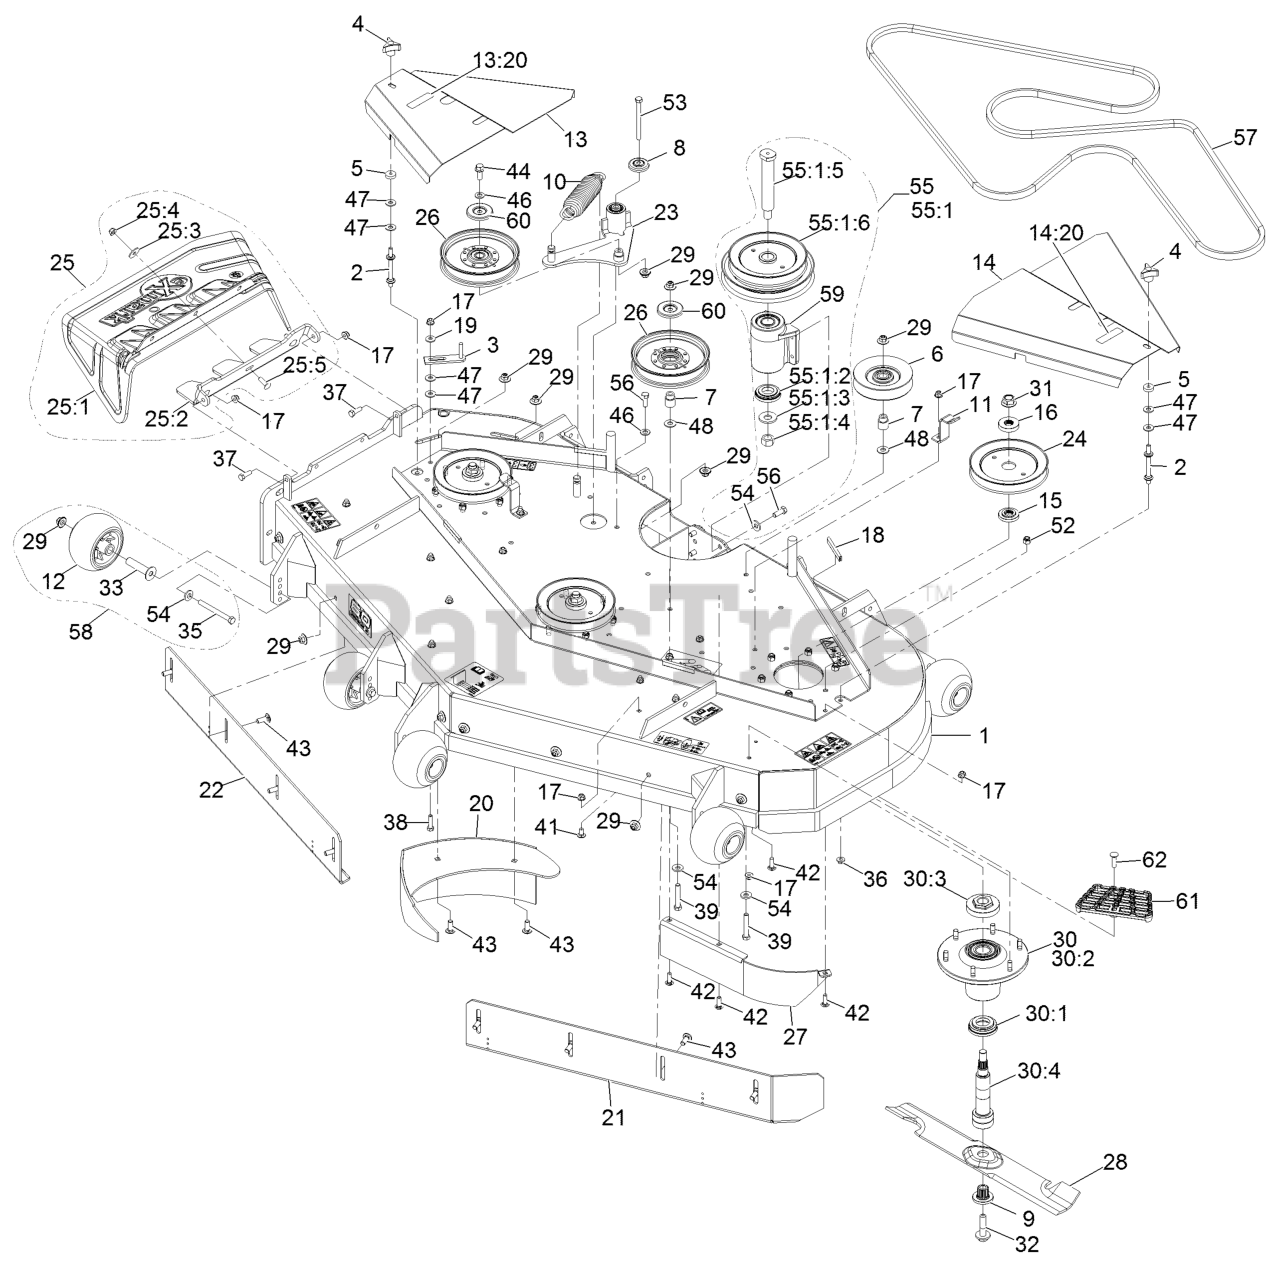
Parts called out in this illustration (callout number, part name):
1	ASM, DECK 605 W/DECALS
2	STUD-SHIELD, BELT (SHORT)
3	GUIDE-BELT
4	KNOB-3 PRONG
6	PULLEY-IDLER
7	BUSHING-IDLER
8	GUARD-TOP
9	BUSHING,SPLINED
10	SPRING-EXTENSION
11	LATCH,BELT SHIELD
12	ROLLER-SCALP, ANTI
13	SHIELD, BELT RH 605 W/DEC
13:20	DECAL-NO STEP
14	SHIELD, BELT LH 605 W/DEC
14:20	DECAL-NO STEP
15	SPACER,SPLINED STEPPED
16	SPACER,SPLINED
17	NUT-HF, NI
18	STRIP-SEAL
19	WASHER-SPRING
20	WLD,DOGLEG 605
21	WLD,BAFFLE FRT ADJ LH 605
22	WLD,BAFFLE FRT ADJ RH 605
23	KIT, IDLER ARM W/BEARINGS
24	SHEAVE, BLADE DRIVE 6.13
25	ASM, DISCHARGE CHUTE
25:1	CHUTE,DISCHARGE LZ
25:2	HINGE,DISCHARGE CHUTE
25:3	WASHER-FLAT
25:4	NUT-HF, NI
25:5	SCREW-CARR
26	IDLER-PULLEY, FLAT 6.00X1
27	BAFFLE,SCROLL 605
28	Blade-High Lift Solid, 20.75
28	Blade,High Lift Notched 20.75
28	Blade-Extreme 2, 20.75
29	Nut-Nyloc 3/8-16 Flg
30	ASM,SPINDLE HOUSING
30:1	GUARD,BOTTOM
30:2	ASM,CUTTER HOUSING
30:3	NUT, SPINDLE 7/8-14
30:4	SPINDLE,DOUBLE SPLINE
31	NUT-FLANGE, CENTERLOCK
32	SCREW,SEMS 1/2-20 X 2.19
33	AXLE, ROLLER
35	SCREW-HH 3/8-16 X 3 3/4 GR 8
37	SCREW-HH
38	SCREW-HH
39	SCREW-HH
41	SCREW-CARR
42	SCREW-CARR
43	SCREW-CARR
44	SCREW-HHF
46	WASHER-FLAT
47	WASHER-FLAT
48	WASHER-FLAT
52	NUT-LOCK, NI
53	SCREW-HH
54	WASHER-BELLEVILLE
55	KIT,JACKSHAFT 60/72-3750
55:1:2	SPACER-GUARD, BOTTOM
55:1:3	WASHER-SPRING
55:1:4	NUT-HEX
55:1:5	JACKSHAFT
55:1:6	SHEAVE, JACKSHAFT DOUBLE
56	SCREW-HH
57	BELT,BLADE DRIVE
58	KIT, ANTI-SCALP ROLLER
59	KIT, JACKSHAFT ASSY
60	SHIELD-DUST
61	STEP-DECK
62	Bolt-Carriage 5/16-18 X 1 1/4
